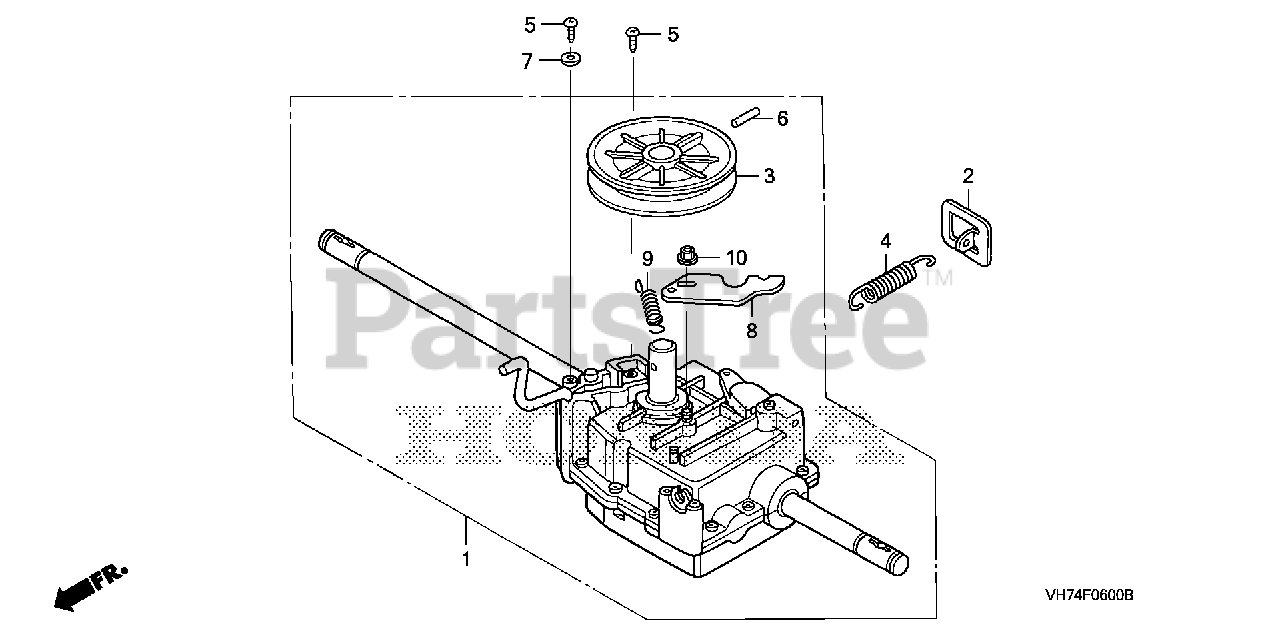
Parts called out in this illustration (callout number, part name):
1	TRANSMISSION ASSY.
2	PLATE, TENSION SPRING
3	PULLEY, DRIVEN
4	SPRING, WHEEL TENSION
5	SCREW, TAPPING (5X12) (PO)
6	PIN, SPRING (5X36)
7	WASHER, PLAIN (6MM)
8	ARM, CLUTCH
9	SPRING, CLUTCH ARM RETURN
10	NUT, LOCK (5MM)
